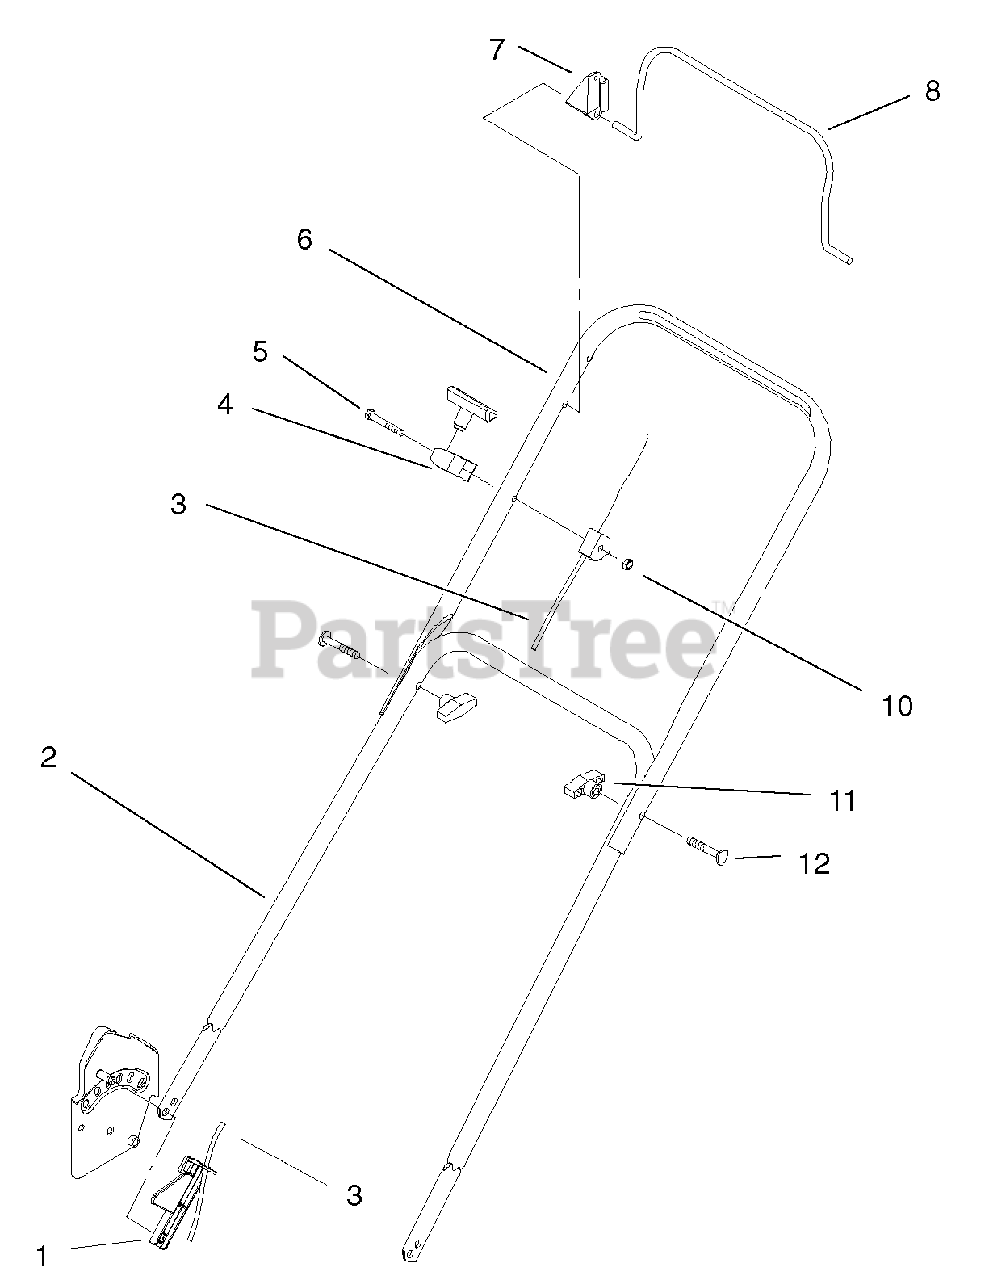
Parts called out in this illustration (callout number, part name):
1	Guard-Cable
2	Handle-Lower
3	Brake Cable ASM
4	Guide-Rope
5	Screw-HH
6	Handle-Upper
7	Stop-Pivot
8	Bail-Brake
10	Nut-Lock, NI
11	Knob-Handle
